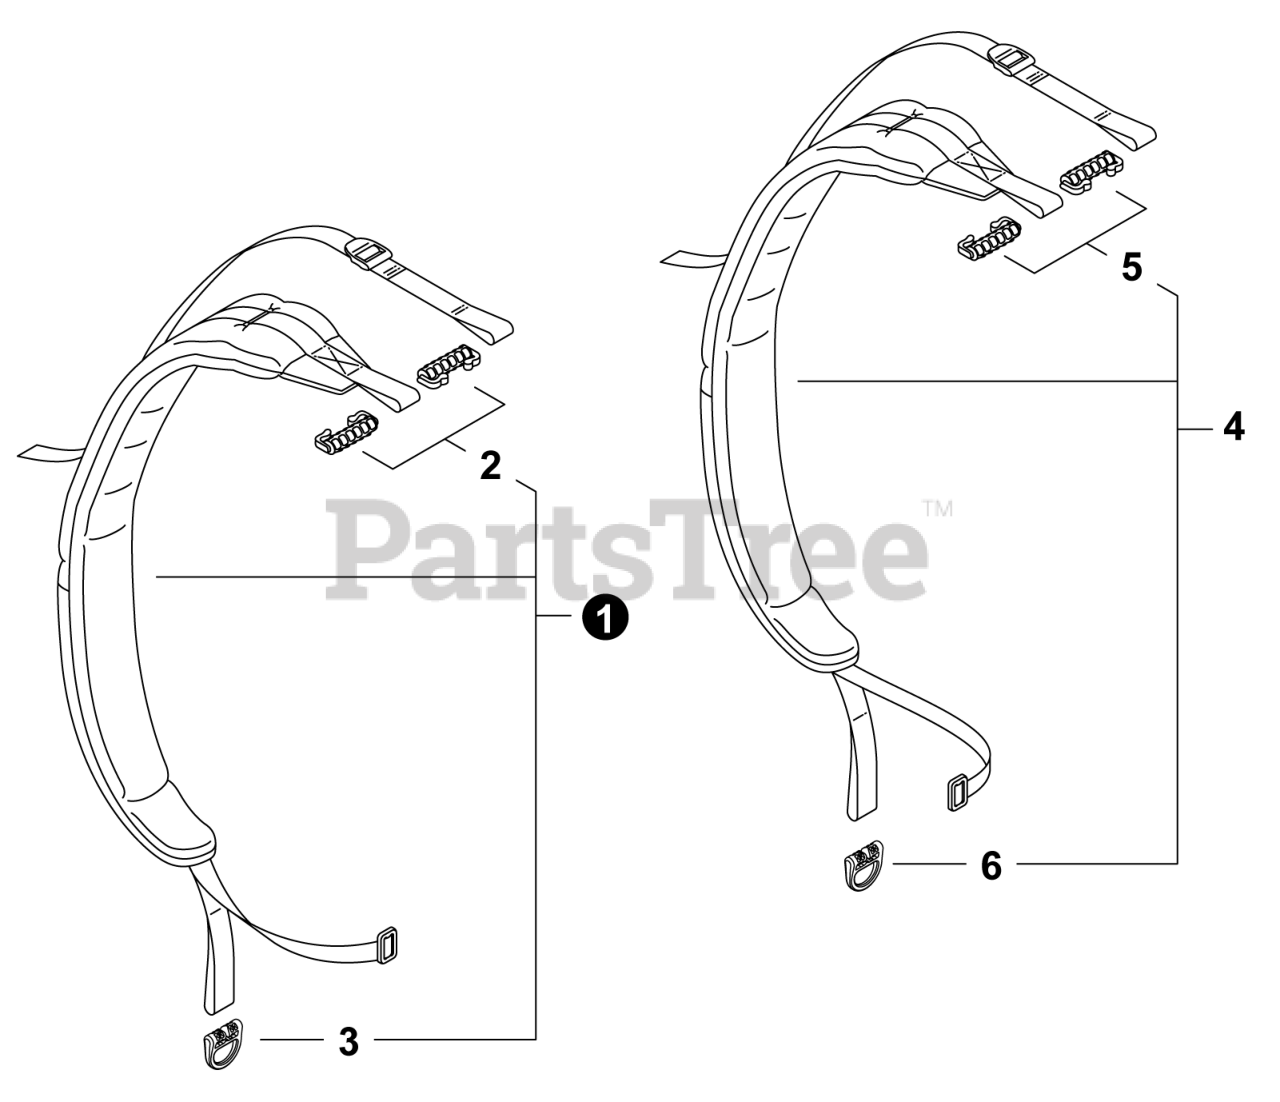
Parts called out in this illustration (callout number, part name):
1	HARNESS ASSY, LEFT
3	BUCKLE, HARNESS
4	HARNESS ASSY, RIGHT
6	BUCKLE, HARNESS
